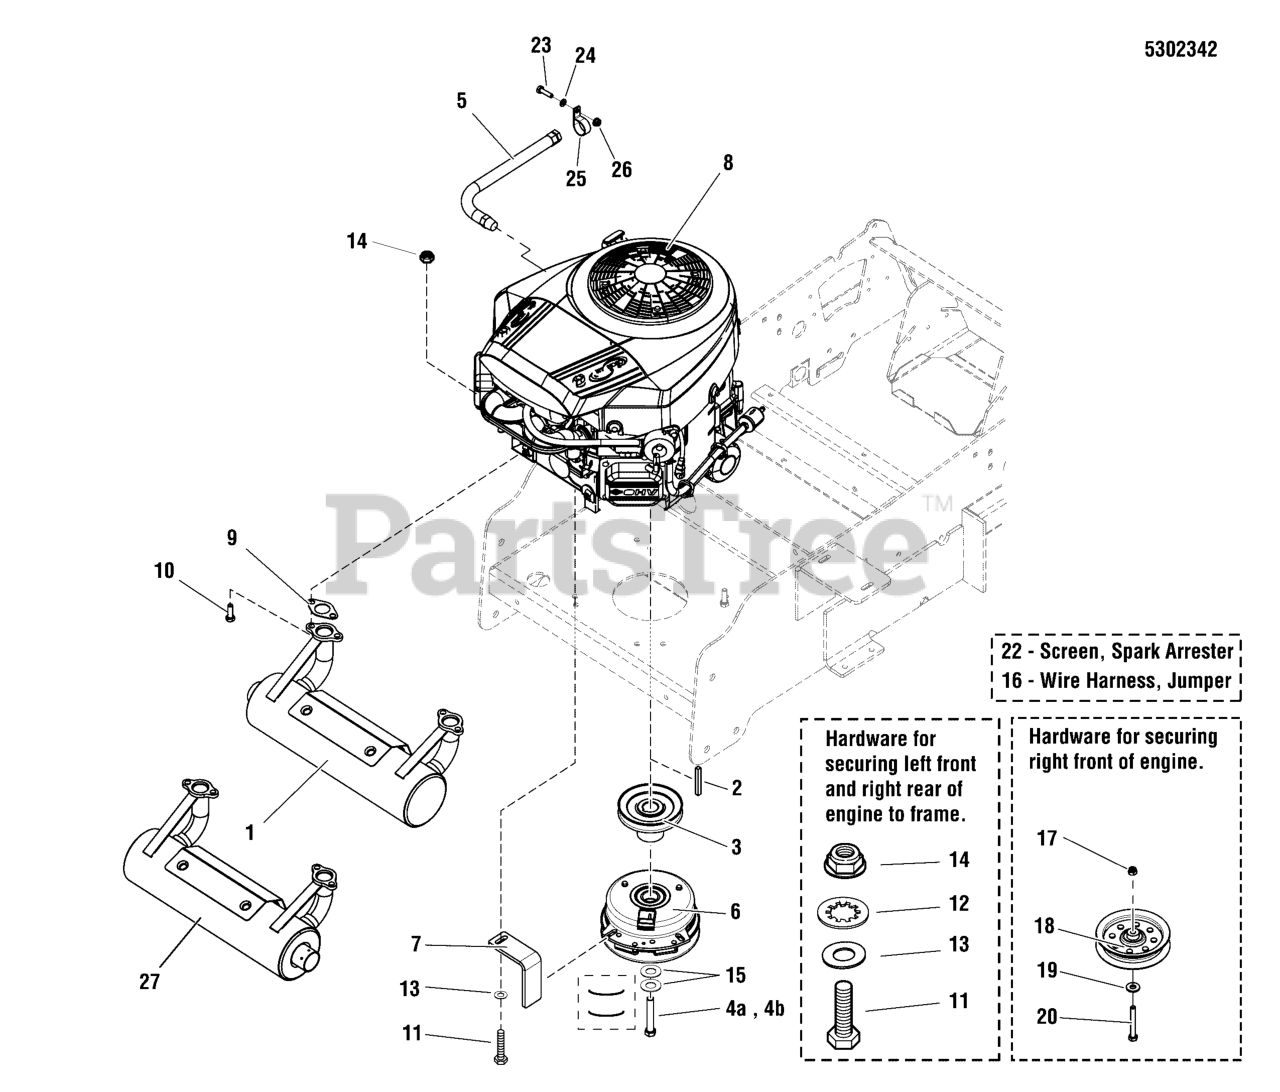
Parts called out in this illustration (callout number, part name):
1	MUFFLER, B&S-ELS
2	KEY, 1/4 SQ X 1
3	PULLEY, PUMP DRIVE, 4.857 OB X 1" BORE
5	HOSE, OIL DRAIN
6	CLUTCH, # 5219-34A, ELECTRIC, IS500Z
7	ANCHOR, CLUTCH - BLK
8	ENGINE, BRIGGS & STRATTON
9	GASKET, Exhaust
11	BOLT, 5/16-24 X 1-3/4, GD8
12	WASHER, 5/16" INT. TOOTH LOCK
13	WASHER, 5/16" SAE
14	NUT, 5/16-24, NYLOCK FLANGE, GD8, CZ
15	BELLEVILLE WASHER 1.1875 X .442 X .089
17	NUT, 5/16-24, NYLOCK FLANGE, GD8, CZ
18	PULLEY, IDLER, STATIONARY
19	WASHER, 3/8 SAE
20	BOLT, 5/16-18 X 2-1/2 GD5 CZ
23	BOLT, 1/4-20 X 1" GD5 CZ
24	WASHER, 1/4 SAE
25	CLAMP, VINYL INSULATED
26	NUT, 1/4-20 HEX NYLOCK FLANGE
27	MUFFLER, RIGHT OUTLET ASSY
